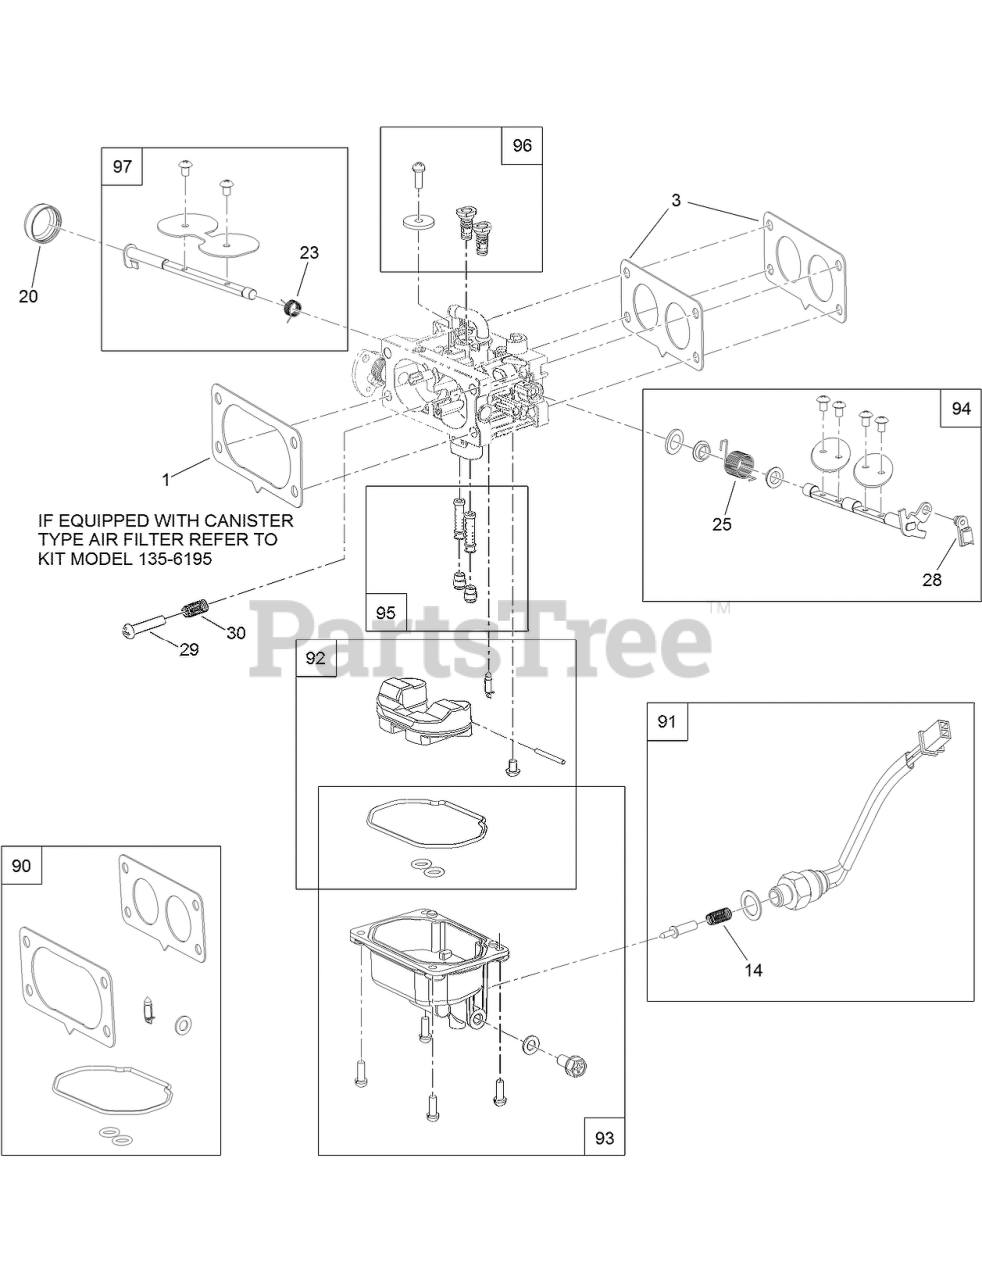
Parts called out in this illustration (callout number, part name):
1	GASKET-CARBURETOR
3	GASKET-CARBURETOR
14	SPRING
20	COVER-SHAFT, CHOKE
23	SPRING
25	SPRING
28	CLAMP-LOCK
29	SCREW-PPH
30	SPRING
90	CARBURETOR REPAIR KIT
91	SOLENOID KIT
92	FLOAT KIT
93	BOWL KIT
94	THROTTLE SHAFT KIT
95	NOZZLE AND JET KIT
96	IDLE JET KIT
97	CHOKE SHAFT KIT
